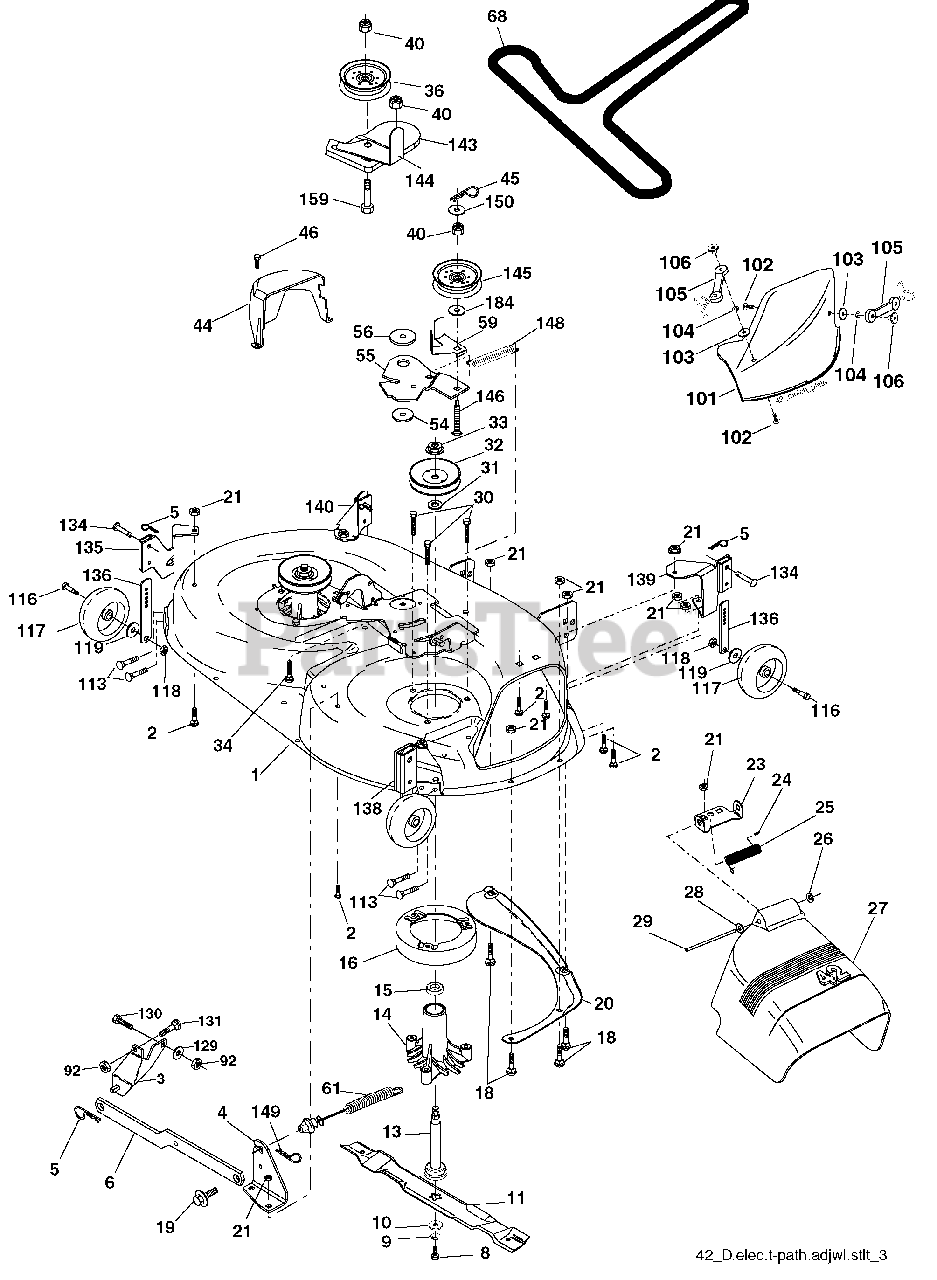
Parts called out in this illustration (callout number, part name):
1	Mower Deck Assembly, 42"
2	Bolt
3	Bracket Asm Fr. Sway Bar 3/42
4	Bracket Asm Deck 42" Sway Bar
5	Retainer Spring
6	Bar Sway Deck
8	Bolt 3/8-24 x 1.25 Gr. 8 patched
9	Washer, Lock
10	Washer, Hardened (The following Blades are available)
11	Blade, Mulching 42” Std (for mulching mowers only)
11	Blade Mower 42” Hi-Lift (for bagging and discharging)
11	Blade Mulching 42” Premium (For better wear when mulching)
13	Shaft As sem bly, Mandrel, Vented
14	Housing, Mandrel, Vented
15	Bearing, Ball, Mandrel
16	Stripper, Mandrel Deck
18	Bolt, Carriage 5/16-18 x 5/8
19	Bolt, Shoulder
20	Baffl e, Vortex
21	Nut
23	Bracket, Defl ector Mower 42"
24	Cap, Sleeve 80 x 112 Blk Mower
25	Spring, Torsion, Defl ector 2 52
26	Nut, Push Phos & Oil
27	Shield, Defl ector 42" Blk
28	Washer 11/32 x 5/8 x 16 Ga.
29	Rod, Hinge 42" 6 75 W/G
30	Screw Thdrol
31	Washer, Spacer Mower Vented
32	Pulley, Mandrel
33	Nut, Toplock
34	Bolt Carr SH 3/8-16 x 1-1/2 Gr.5
36	Pulley, Idler, Flat
40	Nut Lock 3/8-16
44	Guard, Mandrel, LH
45	Retainer
46	Screw, Thdrol 1/4-20 x 5/8 T
54	Washer, Hardened
55	Arm, Idler
56	Spacer, Retainer
59	Guard TUV Idler
61	Spring Ext Elect. Clutch
68	V-Belt, 42" Mower
92	Nut Lock Hex w/Ins. 3/8-16 unc
101	Cover Mulching
102	Screw Pan Hd Phillip
103	Washer #10
104	Washer Lock #10
105	Latch Asm. Mulch/Bagger
106	Nut Weld
113	Bolt 5/16-18 Hex Whs Hd Lckserr
116	Bolt, Shoulder
117	Wheel, Gauge
118	Nut Centerlock 3/8-16
119	Washer 3/8 x 7/8 x 14 Ga.
129	Washer 13/32 x 13/16 x 12 Ga.
130	Bolt Fin HEx 3/8-16 unc x 1 Gr. 5
131	Bolt RDHD SQNK 3/8-16 unc x 1
134	Pin Head Rivet
135	Bracket Asm. Whl Ga. R LH
136	Bar Adjusting Gauge Wheel
138	Bracket Asm Whl Ga. R RH
139	Bracket Asm. Whl Ga. F RH
140	Bracket Asm Whl Ga. F LH
143	Bracket Arm Idler 42"
144	Keeper Belt 42" Clutch Cable
145	Pulley Idler Flat
146	Bolt Carriage Idler
148	Spring Return Idler
149	Retainer Spring Yellow
150	Washer 9/32 x 3/4 x 10 Ga.
159	Bolt Rdhd Sqn 3/8-16 unc x 1-3/4
184	Washer 13/32 x 7/8 x 10 Ga.
184	Mandrel Assembly
184	Replacement Mower, Complete (Std. deck Order separately gauge wheel componants Key Nos. 116- 119)
